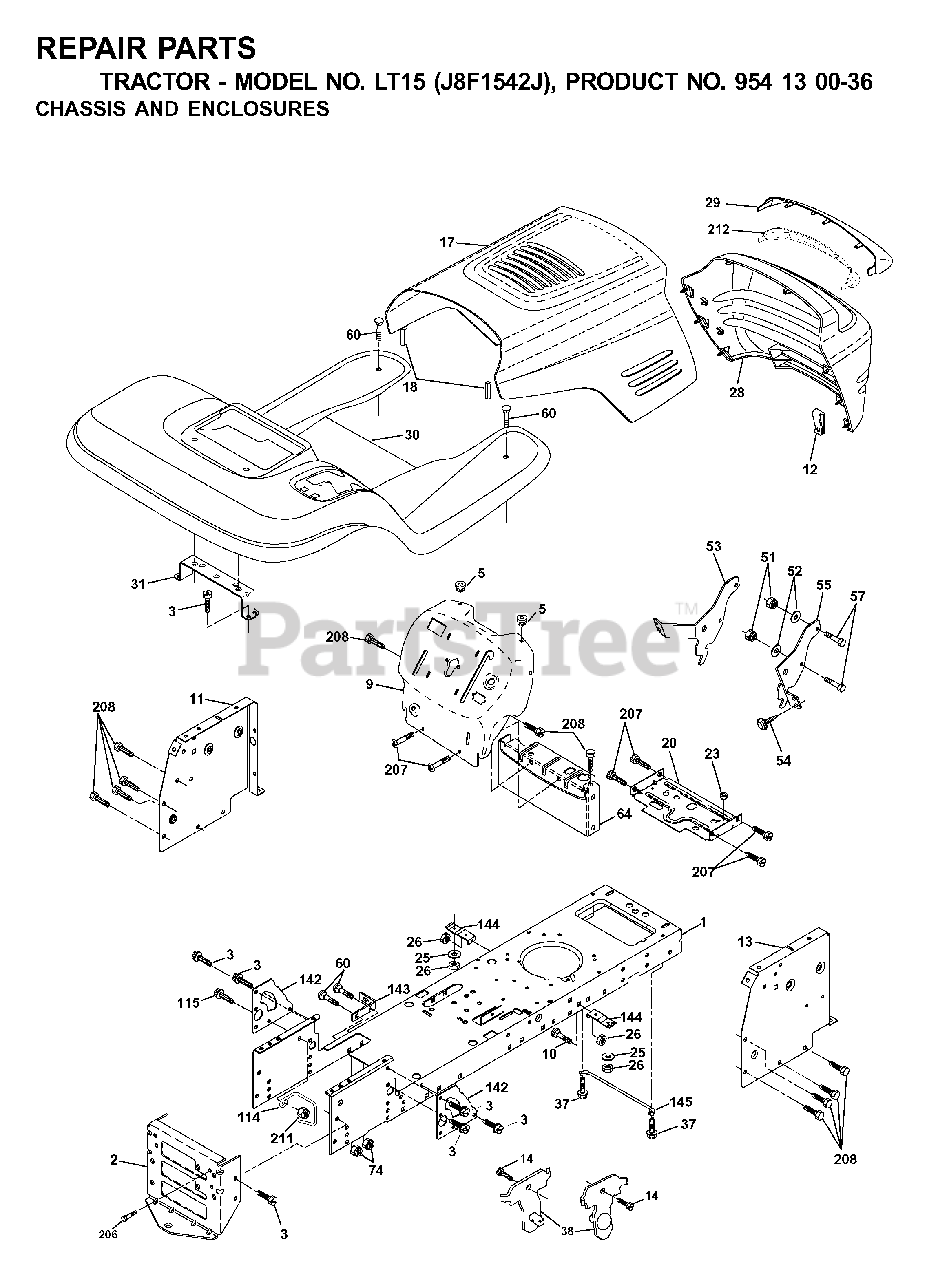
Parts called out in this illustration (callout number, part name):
1	CHASSIS STAMPING
2	DRAWBAR, 12GA
3	SCREW 3/8-16X3/4
5	BUMPER.RUBBER.HOOD
10	BOLT D
11	PANEL DASH LH
13	DASH PANEL RH
14	SCREW LT
18	BUMPER HOOD T
20	PLATE MTG
23	GROMMET T
25	WASHER
26	NUT
37	SCREW LT
38	BRACKET
51	LOCKNUT
52	WASHER
57	BOLT
64	DASH LOWER
74	LOCKNUT
115	SCREW.3/8-16
142	PLATE
143	BRACKET, SWAY BAR
144	BRACKET FOOTREST
145	ROD PIVOT CHASSIS/HOOD
206	SHOULDER BOLT 5/16-18TT
207	SCREW, 5/16-18 X 1/2
208	SCREW 3/8-16X1/2
211	NUT
